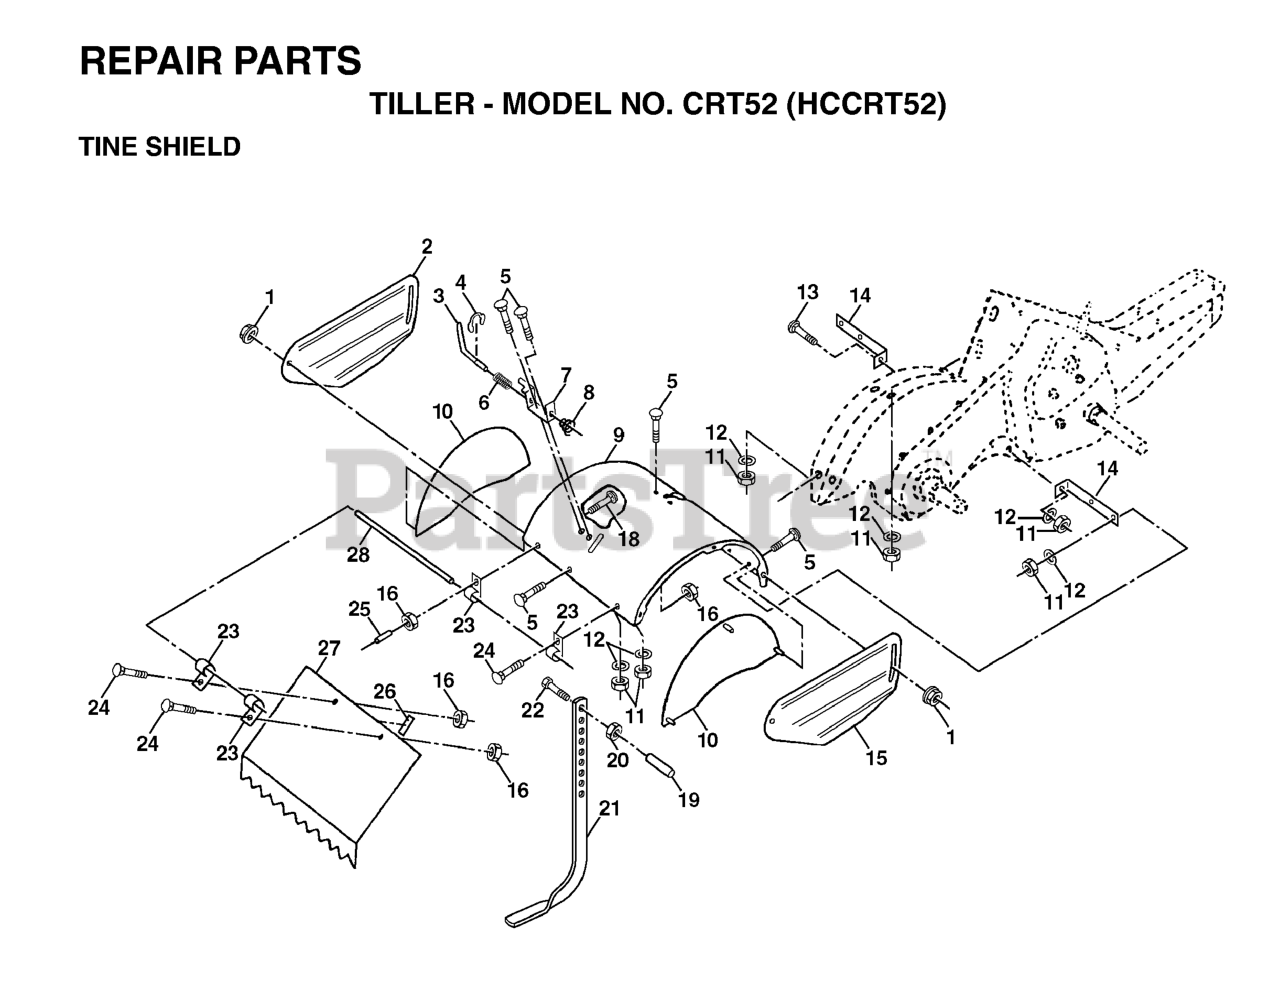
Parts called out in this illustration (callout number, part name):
1	NUT
2	SHIELD SIDE OUTER LH
3	STAKE PIN TI
4	KLIP RING TI
5	RP BOLT 5/16-18 X3/4 ZN/YEL GR
7	BRACKET.LATCH.STAKE.3.20.BLACK
8	SPRING CRT
9	SHIELD
12	WASHER.LOCK.HVY.HLCL.SPR.5/16
13	BOLT.CARRIAGE.5/16-18
14	BRACKET.TINE.SHIELD.TILLER.BLA
15	SHIELD SIDE OUTER RH
16	NUT
17	LOCKWASHER
20	NUT.HEX.3/8-16UNC
21	STAKE.DEPTH.16.CRT.BLACK
22	BOLT.375-16
25	VINYL CAP TI
26	PAD IDLER TI
27	SHIELD LEVELING
28	PIN.HINGE.TILLER
29	SIDE SHIELD
30	LOCKNUT-FLANGE 5/16-18
